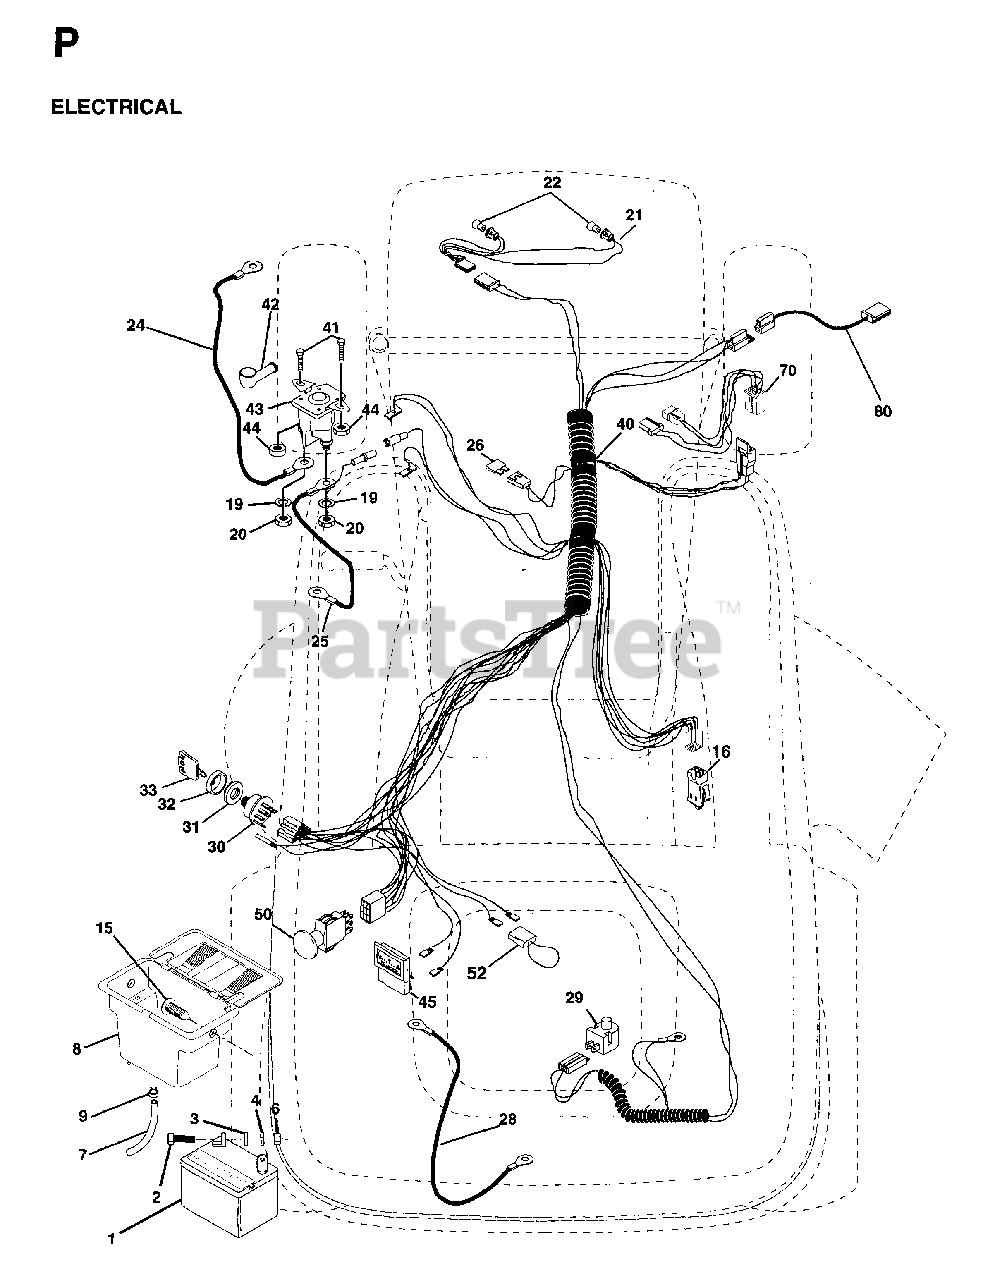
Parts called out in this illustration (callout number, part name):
1	BATTERY.DRY.30.AMP
3	WASHER
4	LOCKWASHER
6	NUT
7	TUBE BATTERY DRAIN
8	CASE BATTERY MECH HINGE
9	HOSE CLAMP T
16	SWITCH INTERLOCK
19	LOCKWASHER
20	NUT
21	HARNESS ASM HDLIG
22	LIGHTBULB
24	BATTERY CABLE GT
25	CABLE BATTERY
28	CABLE T
29	SWITCH SEAT
30	SWITCH.IGNITION.4.POSITION
31	NUT IGNITION
32	COVER SWITCH KEY
40	IGN HARNESS
42	TERMINAL COVER
43	SOLINOID
50	SWITCH PTO 3 PDT
52	WIRE PROTECTION LOOP
70	HARNESS ENGINE
80	HARNESS, CLUTCH
